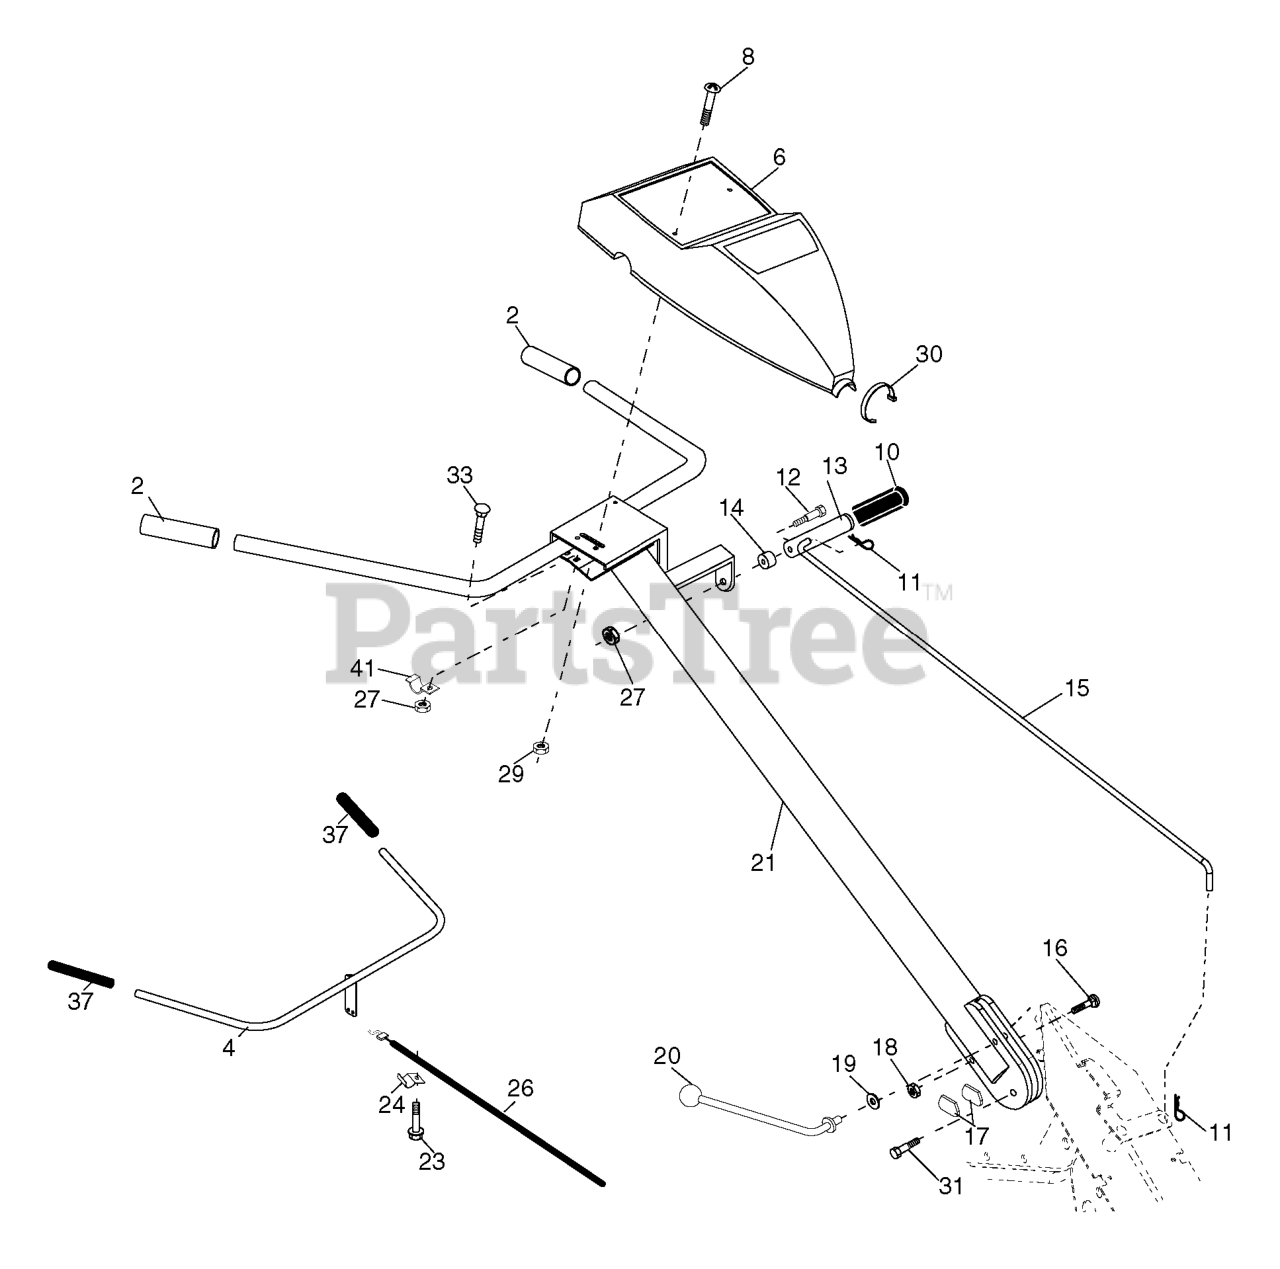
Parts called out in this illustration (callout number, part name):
2	KIT.GRIP.HANDLE.5.00.BLK.VINYL
4	CONTROL BAR ASSY
6	RP PANEL, CONTROL
8	SCREW.PNHD.10-24
10	GRIP T
11	RETAINER M
12	SHOULDER BOLT ST
13	HANDLE.SHIFT.TILLER
14	GROMMET.RUBBER.CRT.TILLER
15	SHIFT ROD CRT
16	BOLT D
17	LOCK.HANDLE.CRT
19	WASHER CRT
20	LEVER.LOCK.CRT
21	REPL BY 532 1805-17
23	TAPPING SCREW
24	CONDUIT.CLIP.PLATED
26	CABLE.CLUTCH
27	NUT T
29	NUT **
30	TIE CABLE CRT
31	BOLT.PIVOT
33	BOLT
37	GRIP BAR CRT(1)
41	CLAMP.BAR.CRT.BLACK
